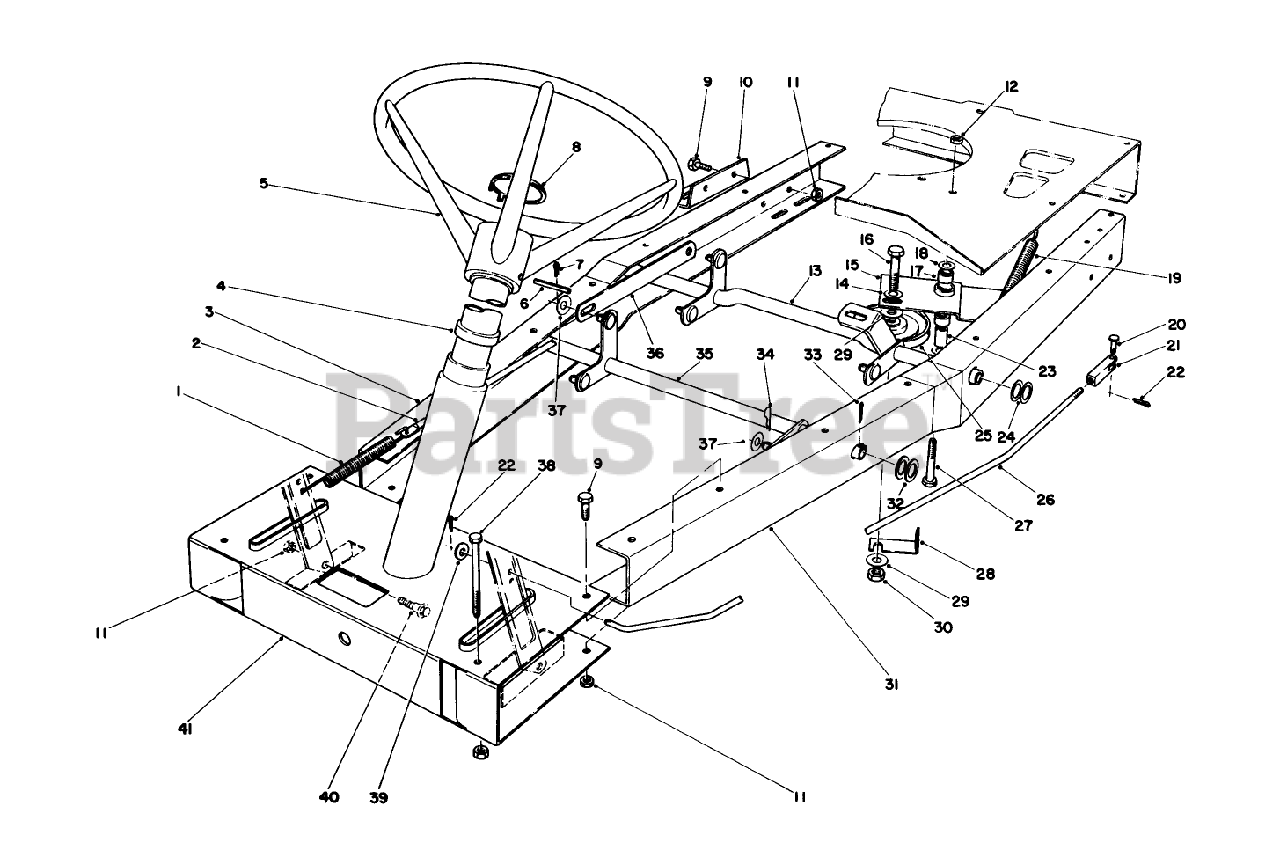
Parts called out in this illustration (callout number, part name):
5	STEERING WHEEL ASM
6	PIN-ROLL
7	PIN-COTTER
9	SCREW-HH
11	NUT-LOCK, NI
12	NUT-HEX
14	WASHER-FLAT
16	SCREW-HH
17	BUSHING
18	WASHER-PLAIN
20	PIN-CLEVIS
22	PIN-COTTER
23	PIVOT SPACER
24	WASHER-FLAT
25	PULLEY-IDLER
27	SCREW-HH
29	WASHER-FLAT
30	NUT-LOCK, SIDE
32	WASHER-FLAT
33	PIN-COTTER
34	PIN-COTTER
37	WASHER-FLAT
38	SCREW-HH
39	WASHER-FLAT
40	SCREW-SHOULDER
